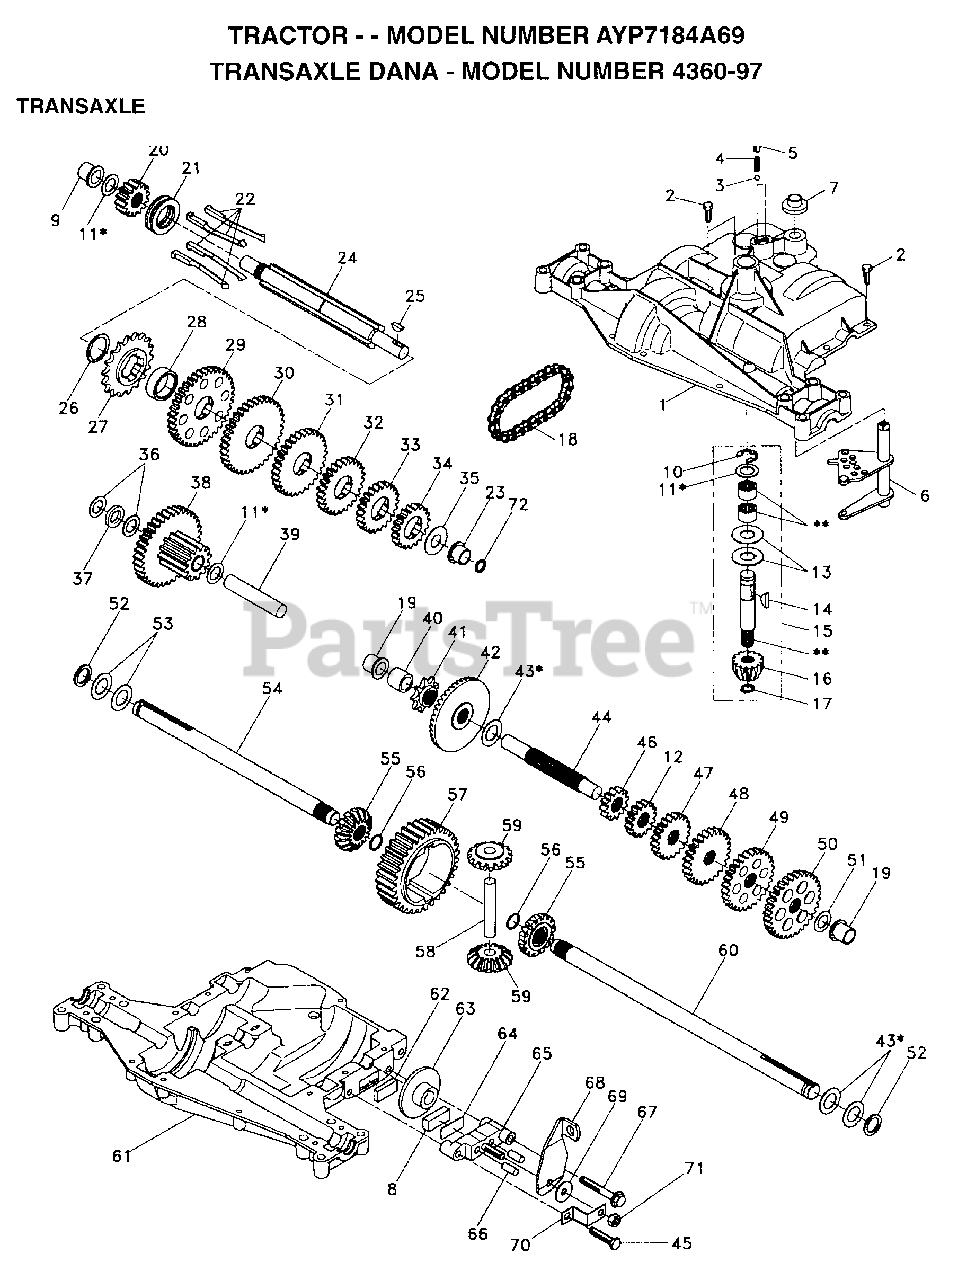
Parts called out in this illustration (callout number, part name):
1	HARNESS.IGNITION
4	"SPRING, DETENT LT"
5	"SCREW, SET LT"
6	SHIFTER.ASM.KIT.
7	SHIFTER BOOT
8	PUCK T
10	RETAINING RING LT
11	ASM KIT SHIM 4689
12	PLUG.PLASTIC
13	WASHER T
14	KEY WOODRUFF-DANA
17	"RING,RETAINING LT"
18	"CHAIN,24 PTCH LT"
19	BEARING.FLNG.5510
20	GEAR SPUR 14 TTH
21	COLLAR CLUTCH
22	KIT.ASM.CLTCH KEY
23	BEARING.FLNG.5511
24	SHAFT INTER 5404
25	WOODRUFF KEY
26	"RING,RETAINING LT"
27	SPROCKET 18T T
28	SPACER YT
29	GEAR SPUR 37 TTH
30	GEAR SPUR 35 TTH
31	GEAR SPUR 30T
32	GEAR 25T LT
33	GEAR SPUR 22 TT
34	SPUR GEAR 19T
35	"WASHER, PLAIN LT"
36	WASHER 025
37	SPACER
38	ASSM GEAR COMB
39	SHAFT IDLER
40	SPACER T
41	SPROCKET 9T LT
43	ASM KIT SHIM
44	SHAFT T
45	"SCREW, TAPPING LT"
46	GEAR SPUR 12 TTH
48	"GEAR, SPUR 25T LT"
49	GEAR 28T T
50	"GEAR, SPUR 31T LT"
51	WASHER 060
52	NEOPRENE WASHER
53	WASHER 031
55	GEAR 15T T
56	"RING,RETAINING LT"
58	SHAFT T
59	"GEAR,MITER 15T YT"
61	HOUSING LOWER TNS
62	PUCK T
63	BRAKE DISC. T
64	SPACER LT
66	PIN T
69	WASHER LT
71	NUT.LOCK.5/16-24
72	SEAL.OIL.DAN.5508
